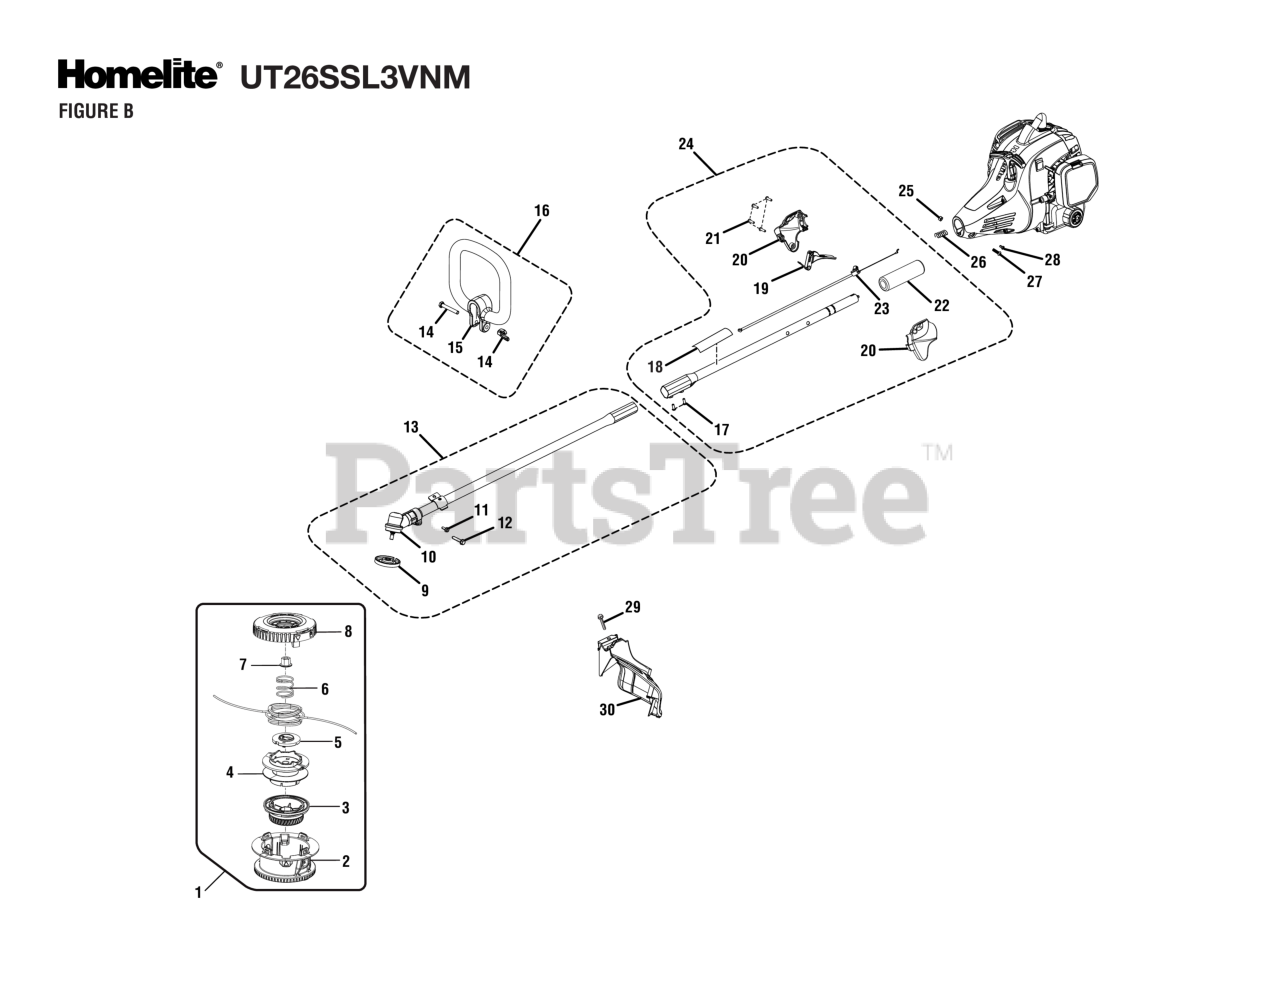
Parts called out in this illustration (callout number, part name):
1	Trimmer Head Assembly (Inc. Key Nos. 2-8)
2	Bump Head
3	Bump Knob (Gray)
4	Spool Assembly
5	String Guide
6	Compression Spring
7	Hex Nut (M8, Left Hand Threads)
8	Locking Assembly
9	FLANGED WASHER
10	Gear Head
11	Screw w/Washer (10-24 x 5/8 in., Hex Hd. T.F.)
12	Screw (1/4-20 x 1-1/4 in., Hex Washer Hd. S.T.)
13	Lower Boom Assembly
14	Fastener Parts Kit
15	Front Handle
16	Front Handle Assembly
17	Set Screw (M5 x 10 mm, Hex Soc. Hd.)
18	Icon Warning Label
19	Throttle Trigger
20	Trigger Handle Assembly
21	Screw (M4 x 20 mm, T20 Torx Pan Hd. T.Fl.)
22	Rubber Grip
23	Throttle Cable
24	Boom Assembly
25	Hex Nut (M6.3 x 1)
26	Compression Spring
27	Screw (M6 x 20 mm, T27 Torx Button Hd.)
28	Screw (M4 x 8 mm, T25 Torx Pan Hd. T.F.)
29	SCREW (#1/4-20 X 1-1/4 in. HEX WASHER HD.)
30	Grass Deflector Assembly
